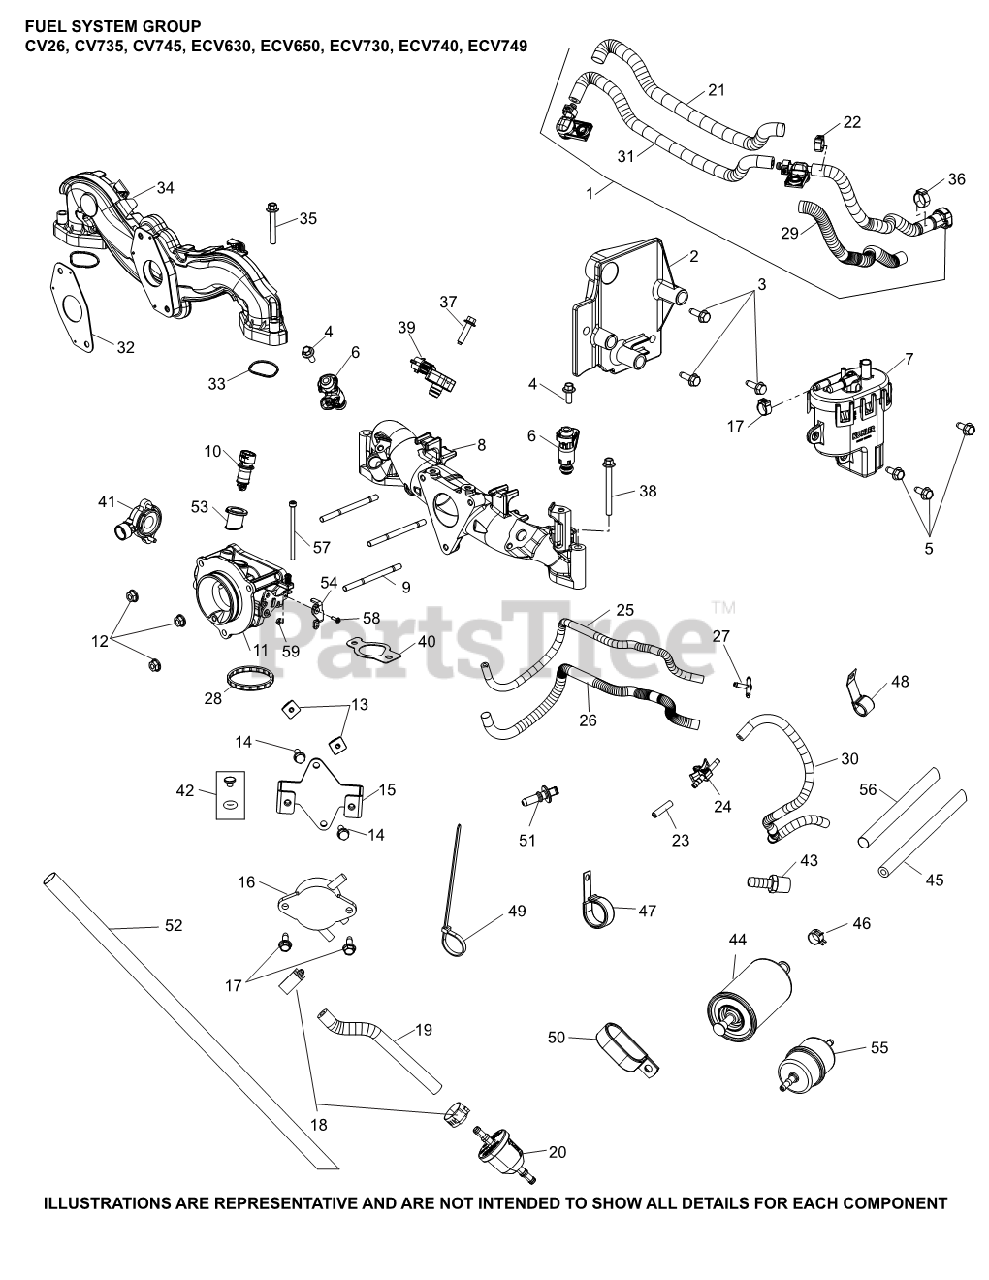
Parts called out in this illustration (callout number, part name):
1	FUEL HOSE ASSY (STRAIGHT FITTING)
2	KIT,BAFFLE, FUEL MODULE
3	SCREW, THREAD FORMING
4	SCREW, FLG M6X1.0X16
5	SCREW, FLG M6X1.0X16
6	INJECTOR, FUEL
7	PUMP, FUEL MODULE - USE 25 393 14-S
8	KIT, MANIFOLD
9	STUD, HDAC-USE M-629085-S
10	SENSOR, AIR TEMPERATURE
11	BODY, THROTTLE ASSEMBLY INCLUDES THROTTLE POSITION SENSOR
12	NUT, FLG M6X1.0
13	NUT, PLASTIC - BLACK
14	SCREW, TAP M6X1.7X18
15	BRACKET, FUEL PUMP MOUNTING
16	PUMP, FUEL
17	SCREW,FLG THD FRM M6X1.0X16-(#25086397S)
18	CLAMP, HOSE (KM)-USE 25 237 31-S
19	HOSE,LW PERM.FUEL 24.00"-USE 25 111 81-S
20	FILTER, FUEL
22	CLAMP, OETIKER
23	CAP, MASKING
24	CONNECTOR, EVAPORATIVE
26	SLEEVE, ANTI-ABRASION
27	TEE CONNECTOR
28	O-RING, THROTTLE BODY
30	HOSE, EVAPORATIVE (15.0)
38	SCREW, FLG M6X1.0X60
39	SENSOR, MAP
40	GASKET, INTAKE MANIFOLD USE 24 041 79-S
41	SENSOR, THROTTLE POSITION
42	KIT, FUEL INJECTOR O-RING
48	CLIP, CABLE
50	CLAMP, INSULATED DOUBLE
